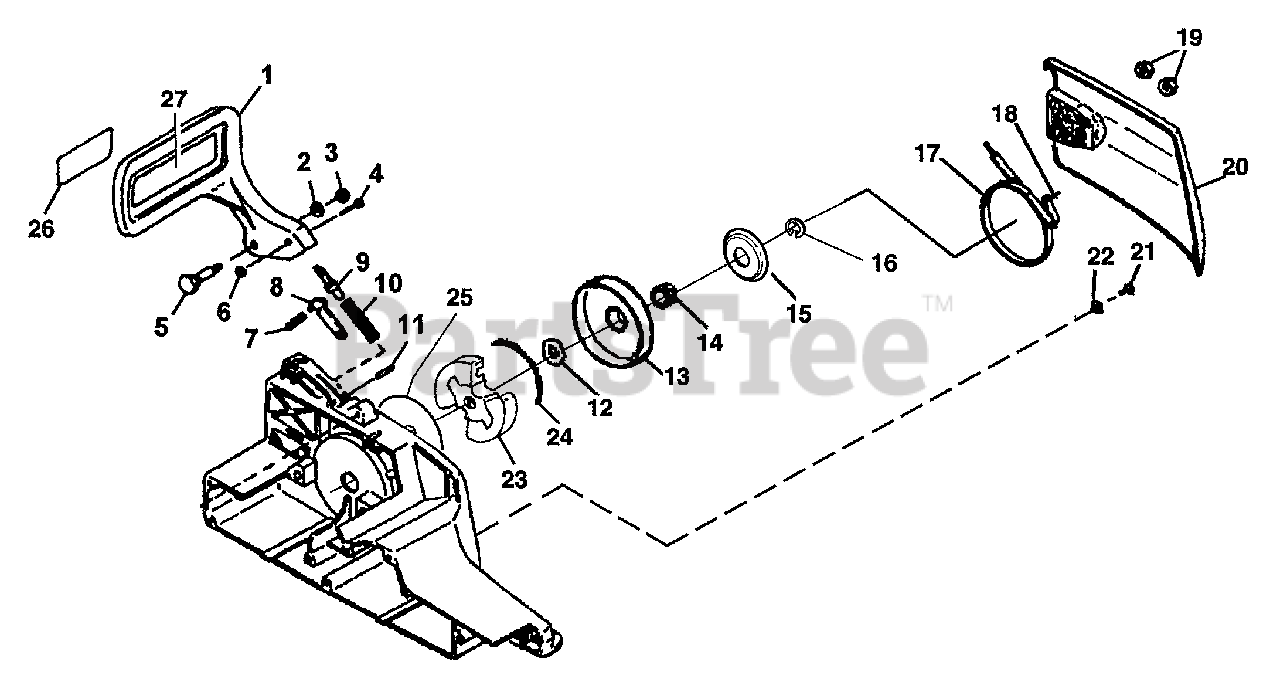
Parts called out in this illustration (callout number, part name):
1	GUARD, HAND
2	WASHER, BELLVILLE
3	NUT (M5)
5	SCREW, SHOULDER
6	RING, RETAINER
7	SPRING, COIL
8	BRAKE LATCH ASSY.
9	ADJUSTER, BRAKE
10	SPRING, COMPRESSION
12	WASHER, THRUST
13	SPROCKET & DRUM & BEARING
14	BEARING, NEEDLE
15	SHIELD, Dust
17	BRAKE BAND ASSY
18	PIN, DOWEL
19	NUT, HEX
20	COVER, DRIVE CASE
21	SCREW, THREAD FORM (#6)
22	RETAINER, BRAKE BAND
23	CLUTCH ASSY.
24	SPRING, CLUTCH
25	WASHER, FLAT
26	LABEL, KICKBACK
27	DECAL, SAFETY
